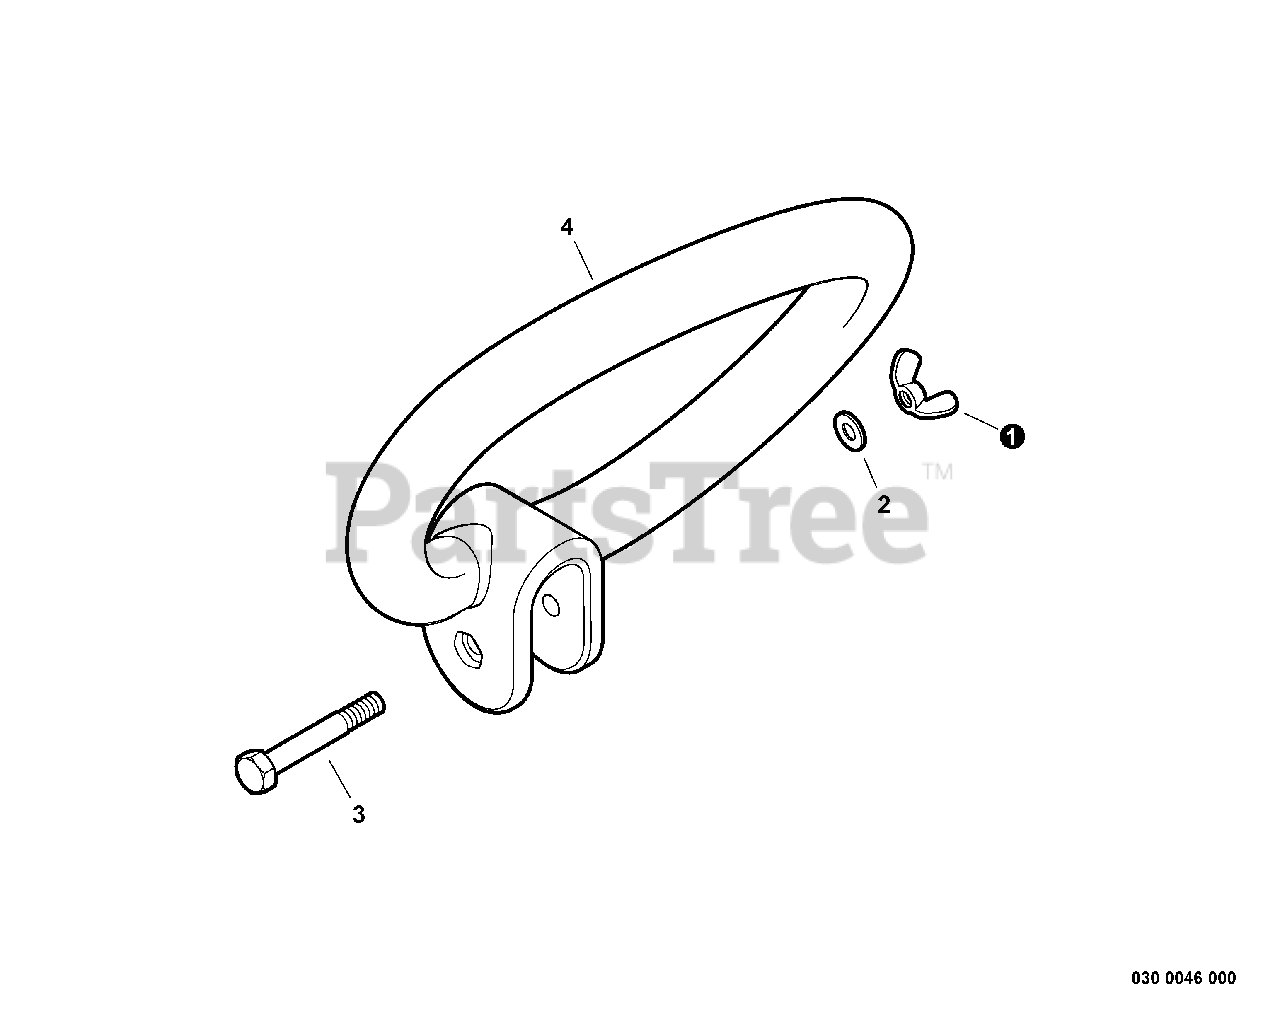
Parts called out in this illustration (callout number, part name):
1	WINGNUT - 1/4-20
2	WASHER - 1/4"
3	BOLT - 1/4-20 X 2"
4	HANDLE - FRONT
